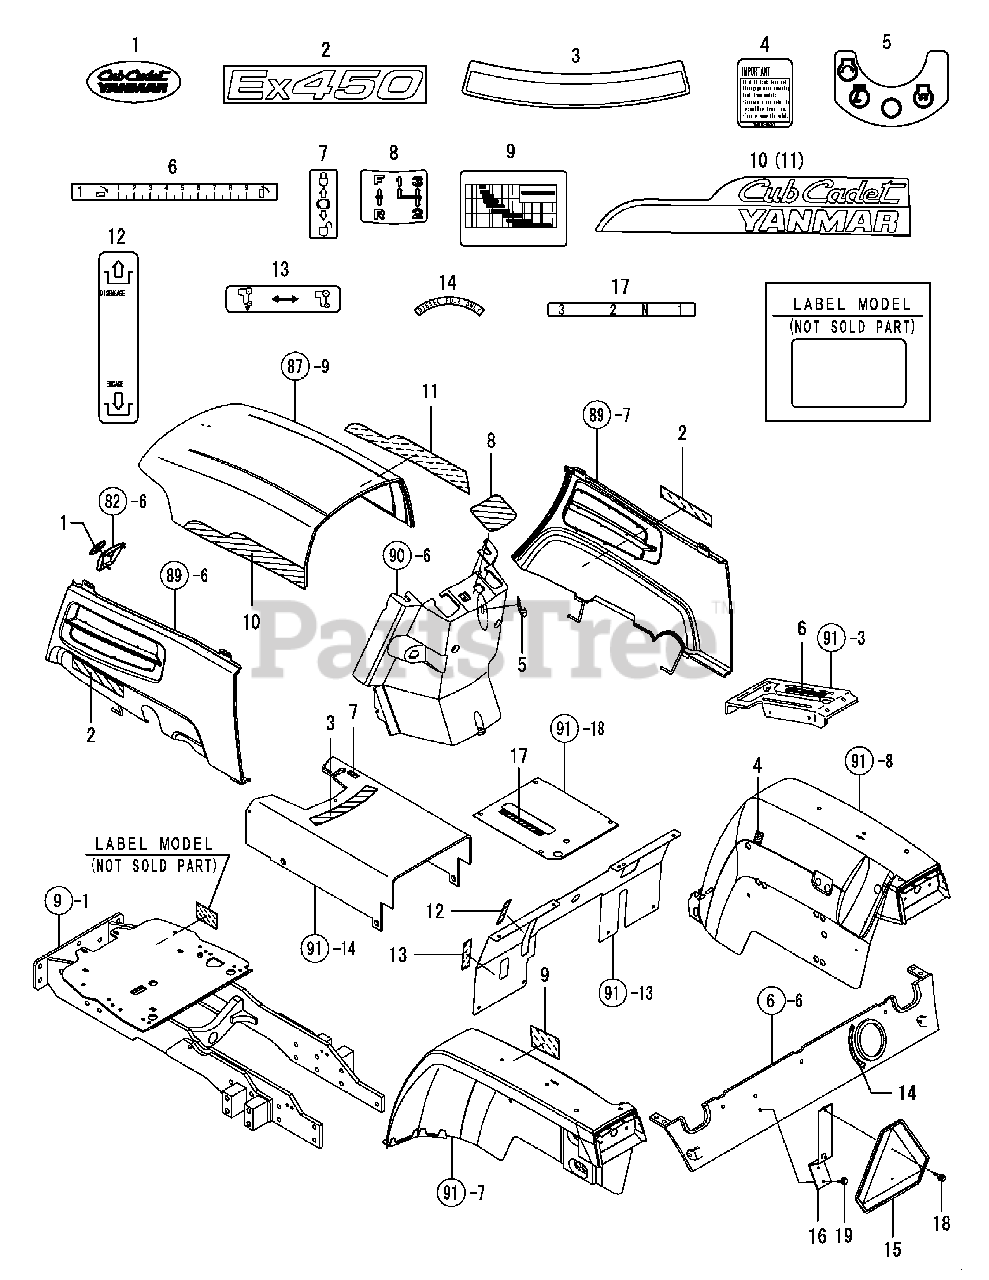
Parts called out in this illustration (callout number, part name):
1	LABEL CENTER LOGO
3	DECAL,COLD START
4	LABEL,IMPORTANT,DIFF
5	LABEL,START SWITCH
8	LABEL,MAIN CHANGE
14	LABEL, FUEL CAUTION
15	EMBLEM,SMV ASSEMBLEY
17	LABEL,SUB CHANGE
18	BOLT M 6X 16 PLATED
